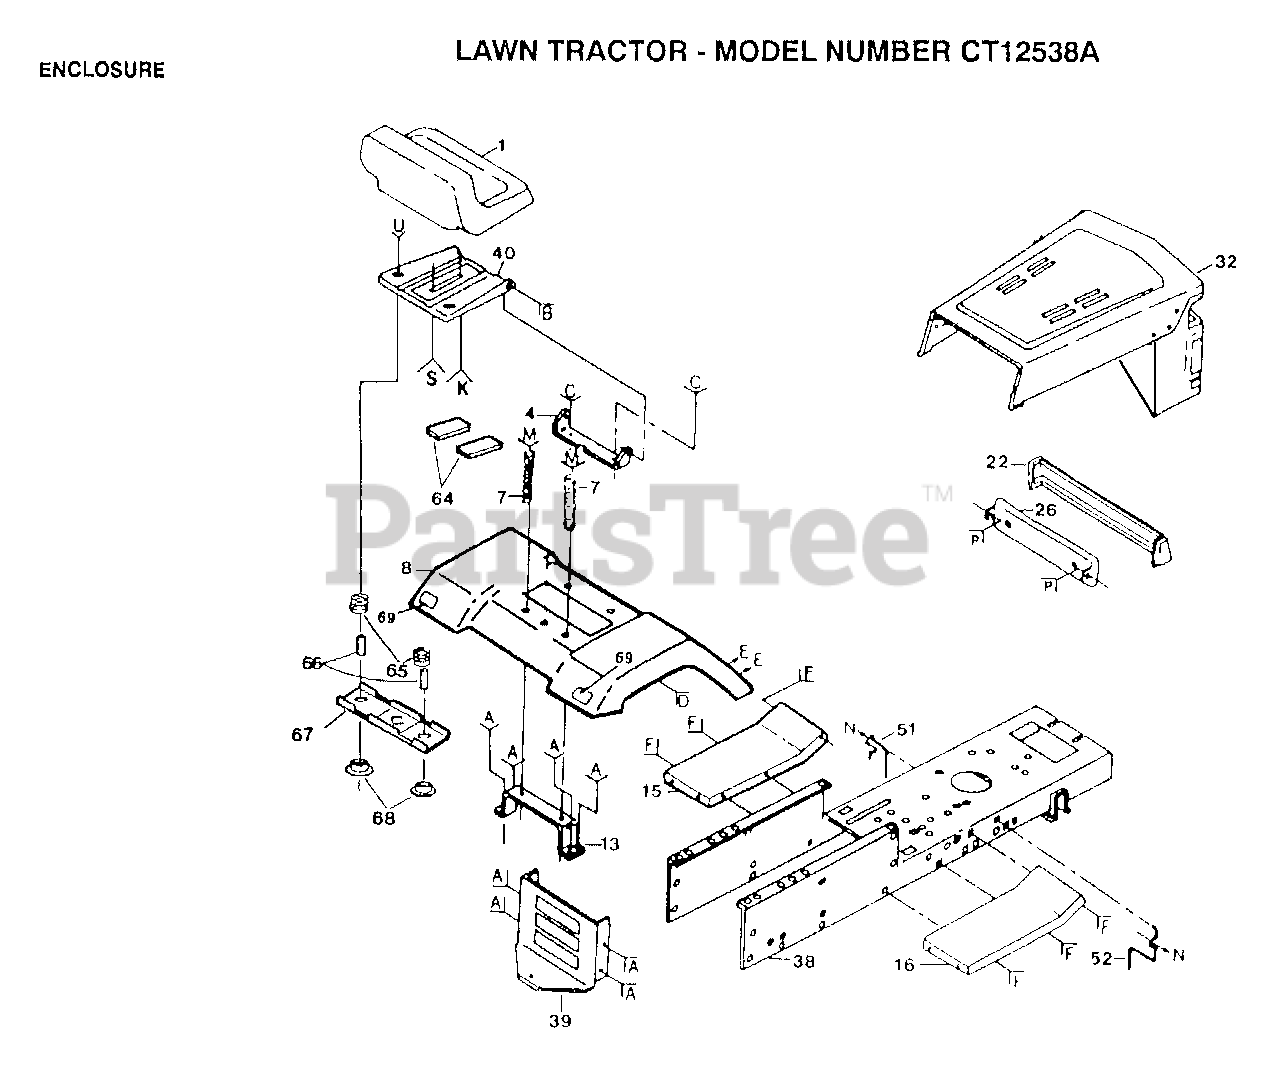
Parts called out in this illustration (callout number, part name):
7	SPRING COMPRESSIO
15	FOOTREST LH
16	FOOTREST
17	BOLT
32	HOOD&GRILL ASS'Y
38	CHASSIS ASS'Y
51	BELT GUIDE
52	BELT GUIDE
64	STRIP FORM
65	SPRING COMPRESSED
66	SPACER SPLIT
67	BRKT SWITCH
68	BUSHING
69	REFLECTOR-TAIL YT
